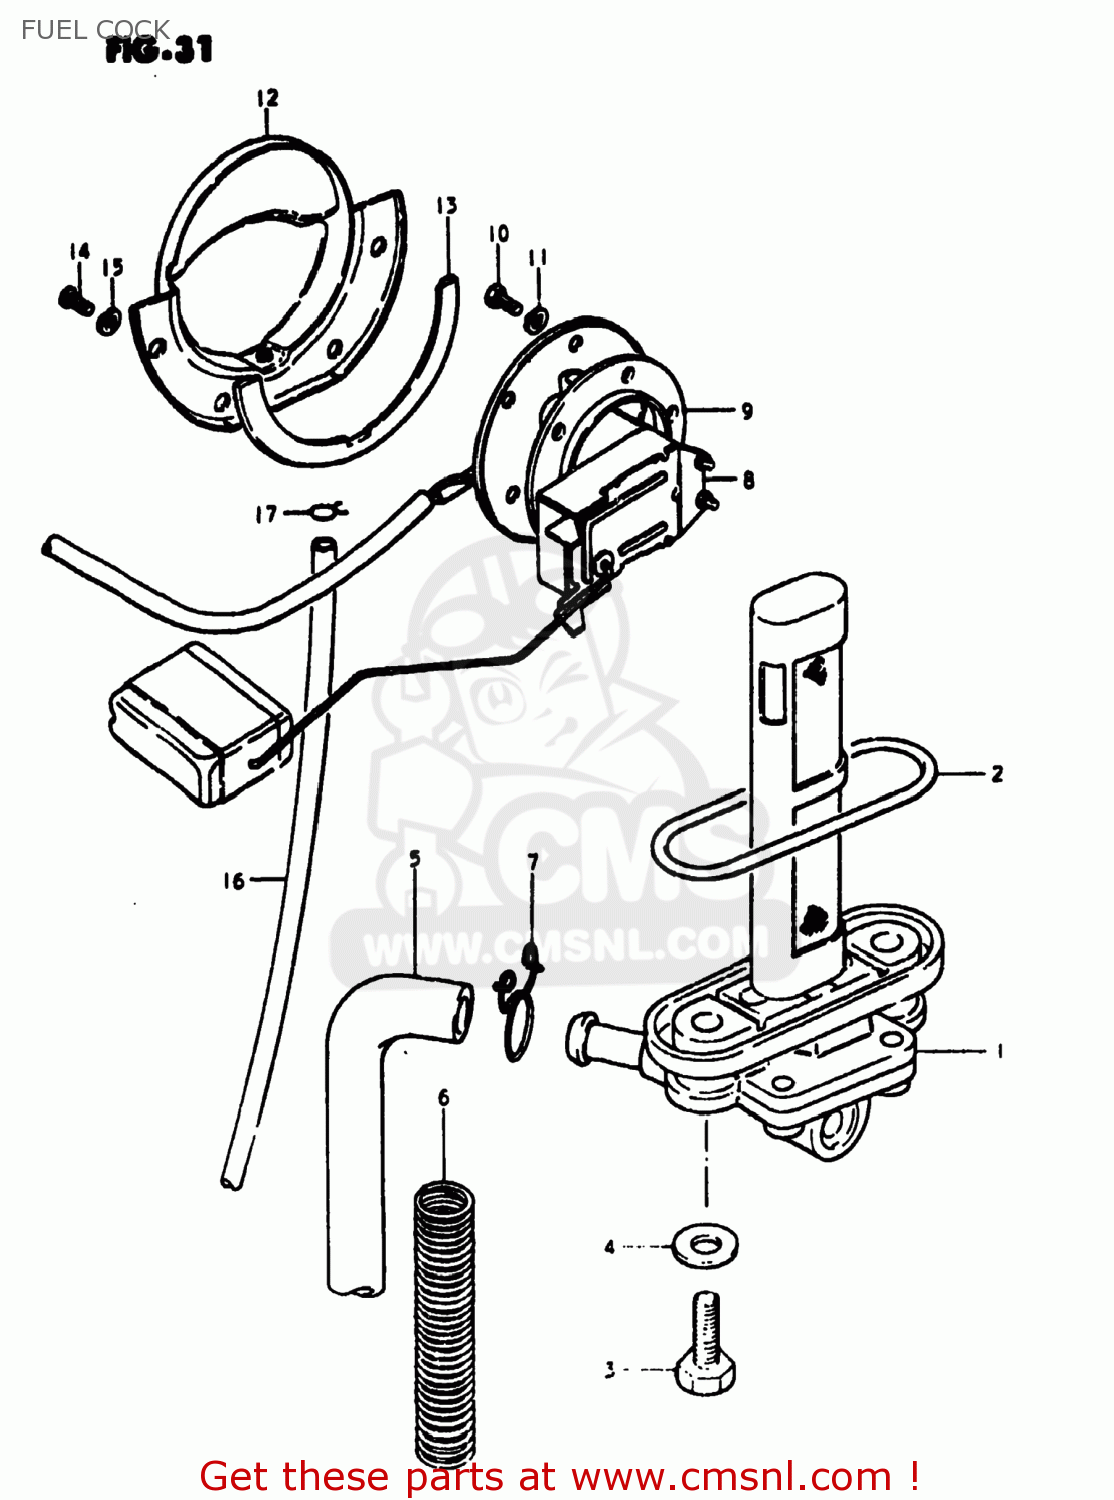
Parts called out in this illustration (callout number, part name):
1	COCK ASSY,FUEL
2	GASKET (NAS)
3	SCREW (6X25)
4	GASKET
5	HOSE
6	SPRING
7	CLIP
8	GAUGE ASSEMBLY,FUEL LEVEL
9	GASKET,FUEL LEVEL GAUGE (NAS)
10	BOLT
11	LOCK WASHER
12	PLATE,FUEL DRAIN
13	GASKET,FUEL DRAIN PLATE (NAS)
14	SCREW
15	LOCK WASHER
16	HOSE,FUEL
17	CLIP
